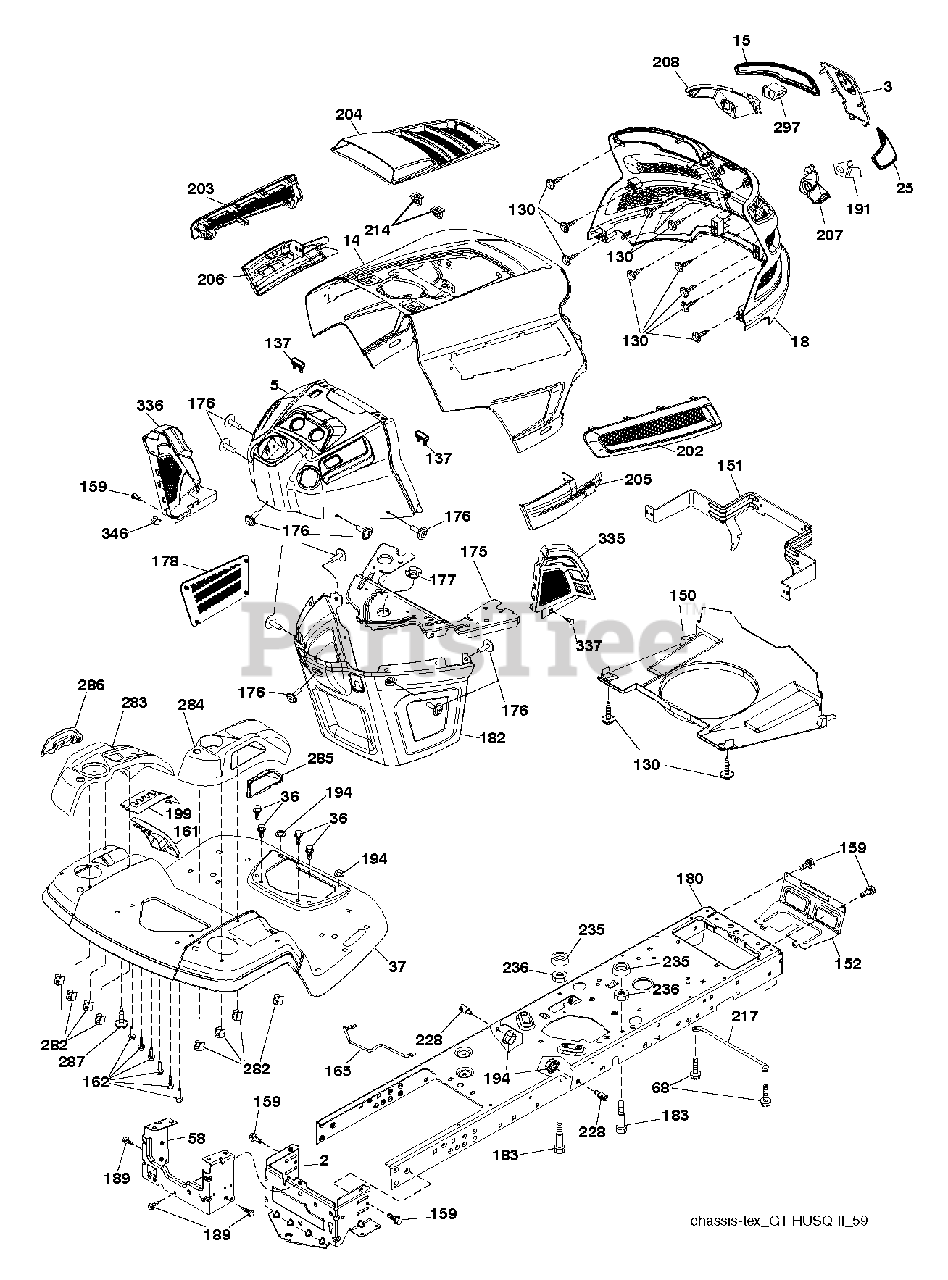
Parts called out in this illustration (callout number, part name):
2	DRAWBAR.LOWER.2PC.18/22
3	APPLIQUE.SUBASM.GT.HUSQ.II
5	DASH.UPPER.ASSY.GT2.DUAL
14	HOOD.ASM.HUSQVARNA.GT.TEX.422
15	LENS.HEADLIGHT.LH.GTII.2011
18	GRILLE.SUBASM.GT.HUSQ.II
25	LENS.HEADLIGHT.RH.GTII.2011
36	SCREW 5/16"
37	FENDER.TLT.FS.W/CPH/FW/RSF.ORN
58	DRAWBAR UPPER 2PC SMALL FENDER
68	SCREW LT
130	SCREW.#10 X 0.750.BOS
137	BUMPER DASH
150	AIR.DUCT.GTV.BLACK
151	BRACKET.PIVOT.HOOD.GT.HUSQ.II
152	SHIELD.BROWNING.PNT.GT.V2
159	SCREW, 3/8-16X3/4
161	WINDOW.FUEL.LT.HUSQ.TEX.498
162	SCREW.HI-LO.CONSOLE
165	SUPPORT.TANK.REAR.B/TE
175	PLATE.CROSSMEMBER.HUSQ
176	SCREW.#10-24X5/8.RN.QU
177	BUSHING, STEERING
178	CARGO.ASM.NET.TXGT.W/C
180	CHASSIS.STAMPING.LT/GT
182	DASH.LOWER.COMMON.12V.ADAPTOR
183	BOLT.5/16-18X1-1/4 FULL THD
189	SCREW
191	INSERT.REFLECTIVE.RH.HUSQ.GTII
194	NUT LOCK HEX FLANGE 5/16-18
199	PLATE.DECK.LIFT.HUSQ.LT
202	VENT.SIDE.RH.GT.HUSQ.II.
203	VENT.SIDE.LH.GT.HUSQ.II.498
204	VENT.TOP.HUSQ.GT2
205	SIDE.TRIM.RH.GT.HUSQ.II
206	SIDE.TRIM.LH.GT.HUSQ.II.GRAY
207	BEZEL LIGHT.RH.GT.II.MYLAR
208	BEZEL LIGHT.LH.GT.II.MYLAR
214	CLIP.RETAINER.TINNER.
217	ROD.PIVOT.HOOD
228	STUD.FASTNER.W/ANTI-ROTATE
235	SPACER FENDER
236	NUT.CENTERLOCK.5/16-
282	CLIP.RETAINER.CONSOLE.LT.HUSQ
283	CONCOLE.CNTRL.PDL.HUSQ.LT.498
284	CONSOLE.DECK.LIFT.R.SDFL.HUSQ
285	CONSOLE INSERT RH
286	CONSOLE.INSRT.LH.HUSQ.LT.BLACK
287	SCREW 1/4X20
297	INSERT.REFLECTIVE.LH.HUSQ.GTII
335	COVER.RH.CLOSE.OUT.BLACK
336	COVER-LH.LOWER.DASH.GT2.BLACK
337	CLIP.XMAS.TREE.ITW.2622-00
346	CLIP,INSULATOR
